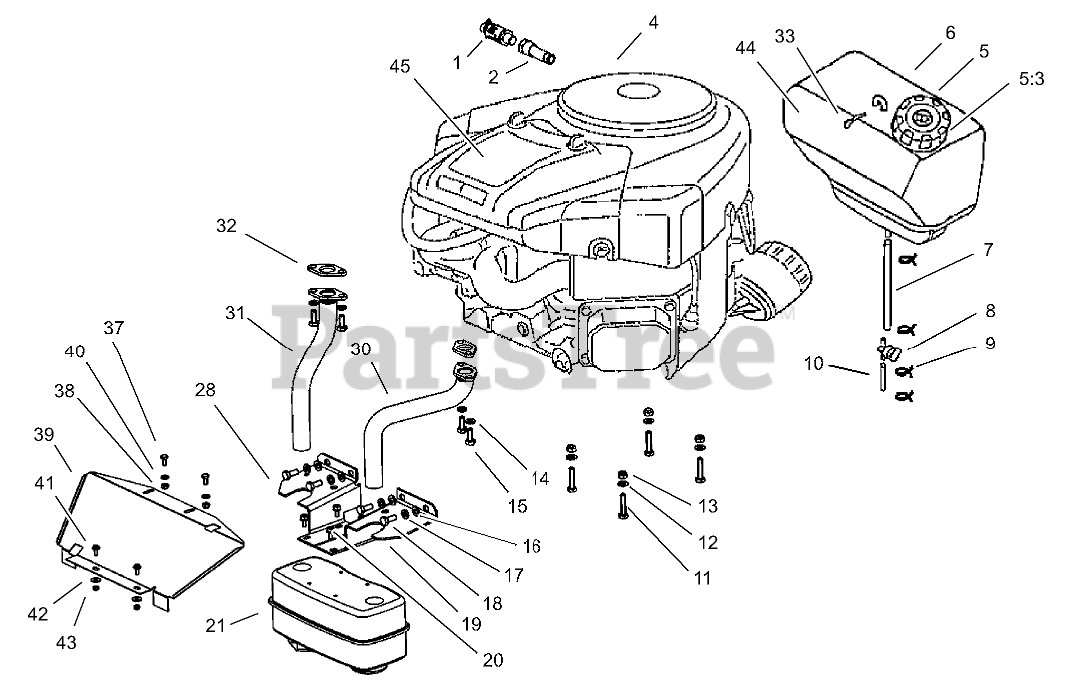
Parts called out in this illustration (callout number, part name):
1	VALVE-OIL DRAIN
2	Coupler-Oil Drain
5	GAS CAP ASM
5:3	GASKET-CAP, GAS
6	TANK-FUEL
7	LINE-FUEL
8	VALVE-TANK, FUEL
9	CLAMP-LINE, FUEL
10	LINE-FUEL
11	SCREW-HH
12	WASHER-PLAIN
13	NUT-LOCK, NI
14	WASHER-SPRING
15	SCREW-HH
16	WASHER-PLAIN
17	WASHER-SPRING
18	SCREW-HH
19	GUARD-MUFFLER, LH
21	MUFFLER
28	GUARD-MUFFLER, RH
30	TUBE-EXHAUST, LH
31	TUBE-EXHAUST, RH
32	GASKET-EXHAUST
33	PIN-HAIR
37	SCREW-HH
38	NUT-LOCK
39	SHIELD-HEAT
40	WASHER-FLAT
42	WASHER-FLAT
43	NUT-LOCK
44	TANK-FUEL W/CAP
45	DECAL-ENGINE
